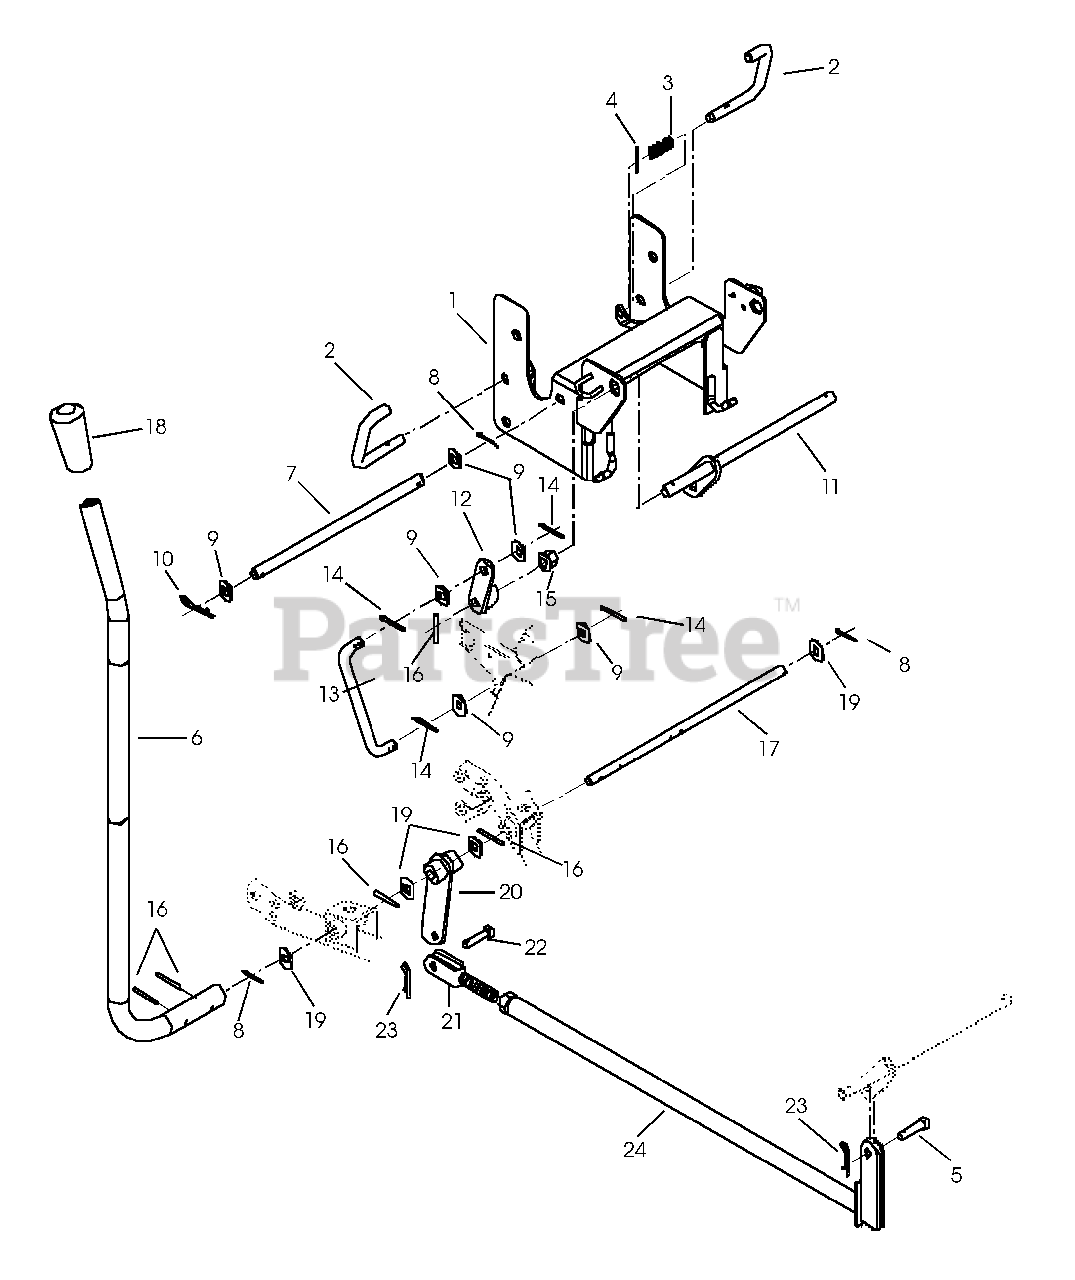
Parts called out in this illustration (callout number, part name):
1	FRAME, PIVOT
2	PIN, LATCH
3	SG-COMP .072X.77X1.75
4	PIN-ROLL .188X1.00
5	CLEVIS PIN - .500 DIA. X 1.000
6	LEVER
7	ROD, PIVOT
8	@PIN-CTR .12X1.25 EXTPRSQCT YZ
9	@WSHR-FL-STL.656X1.31X.095 YWZ
10	PIN-HAIR-INT .17X.68X3.50 YWZC
11	PIVOT ROD
12	ARM, LIFT
13	LINK, LIFT
14	@PIN-CTR .12X1.00 EXTPRSQCT YZ
15	BSHG-FLG .750X.873HEXX.53X1.18
16	PIN-GRV .250X1.50 TP A
17	PIVOT ROD
18	GRIP,HANDLE BAR
19	WSHR-FL-STL.754X1.125X.062YWZC
20	LEVER, ACTUATOR
21	CLEVIS R.H.
22	PIN-CLEV .494X1.25 YWZC
23	PIN-HAIR INT .14X.4X2.75
24	TUBE, LIFT
